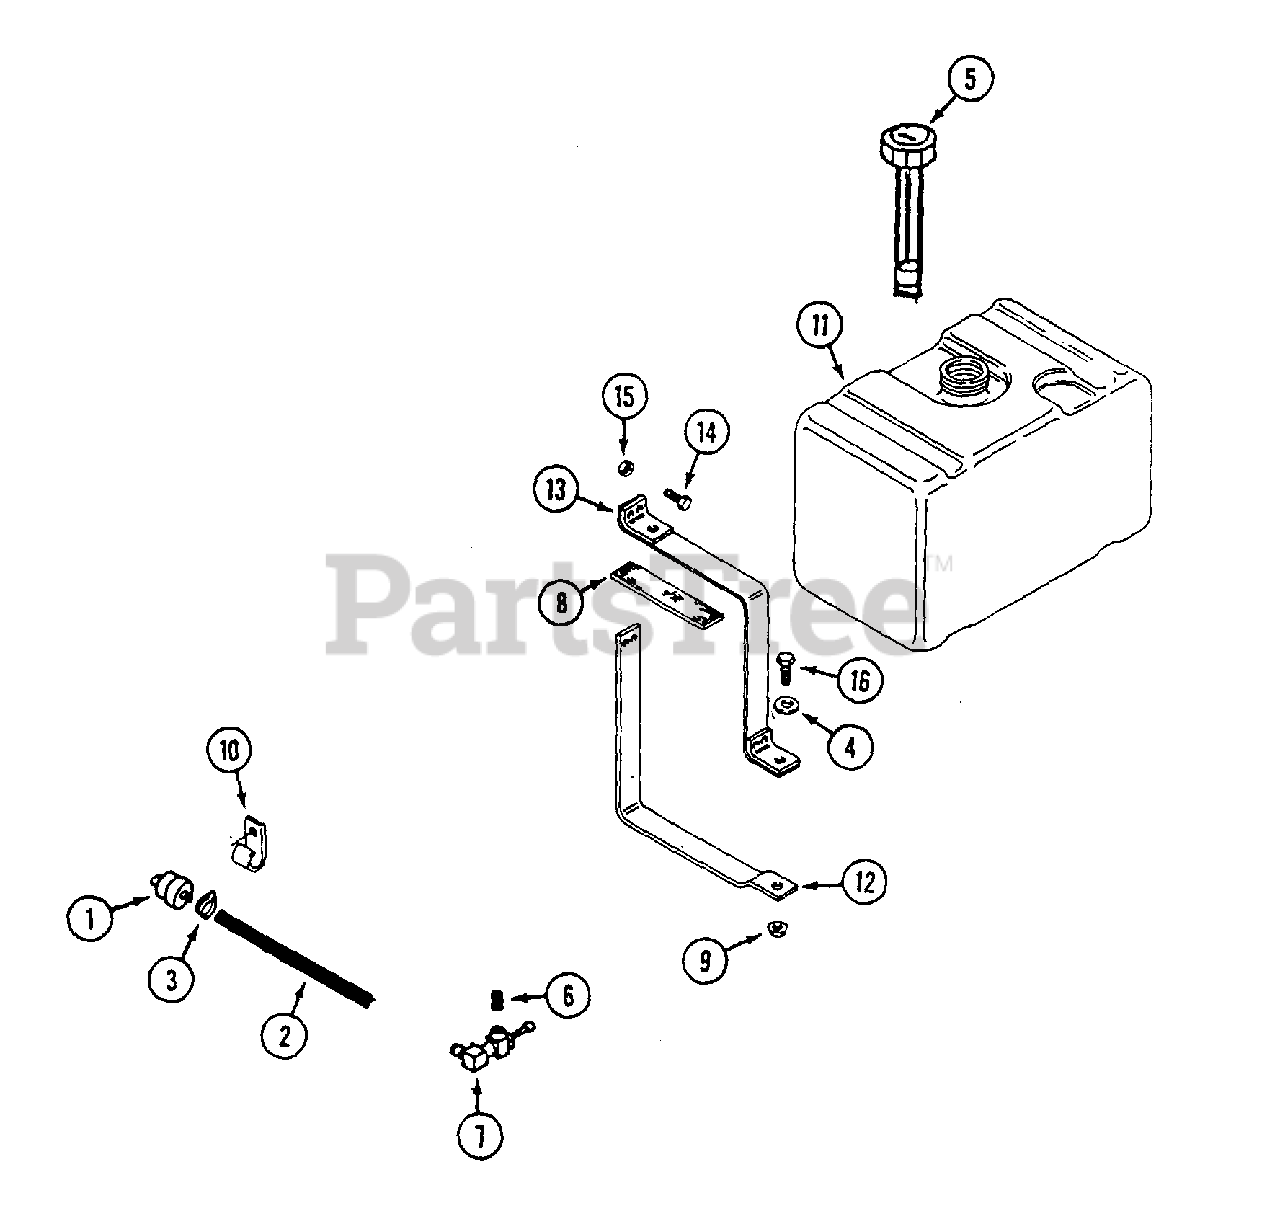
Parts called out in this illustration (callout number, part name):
1	FILTER - fuel
2	HOSE - fuel
4	WASHER - 5/16"
5	CAP - fuel tank
6	NIPPLE - pipe 1/8"
7	VALVE - shut off
8	CUSHION - reservoir
9	NUT - 5/16" - 18 flange lock
10	CLIP - "J" fuel line
11	TANK - fuel
12	BRACKET - fuel tank
13	STRAP - fuel tank
14	BOLT - 1/4" - 20 lock
15	NUT - 1/4" - 20 lock
16	BOLT - 5/16" 18 x 1"
